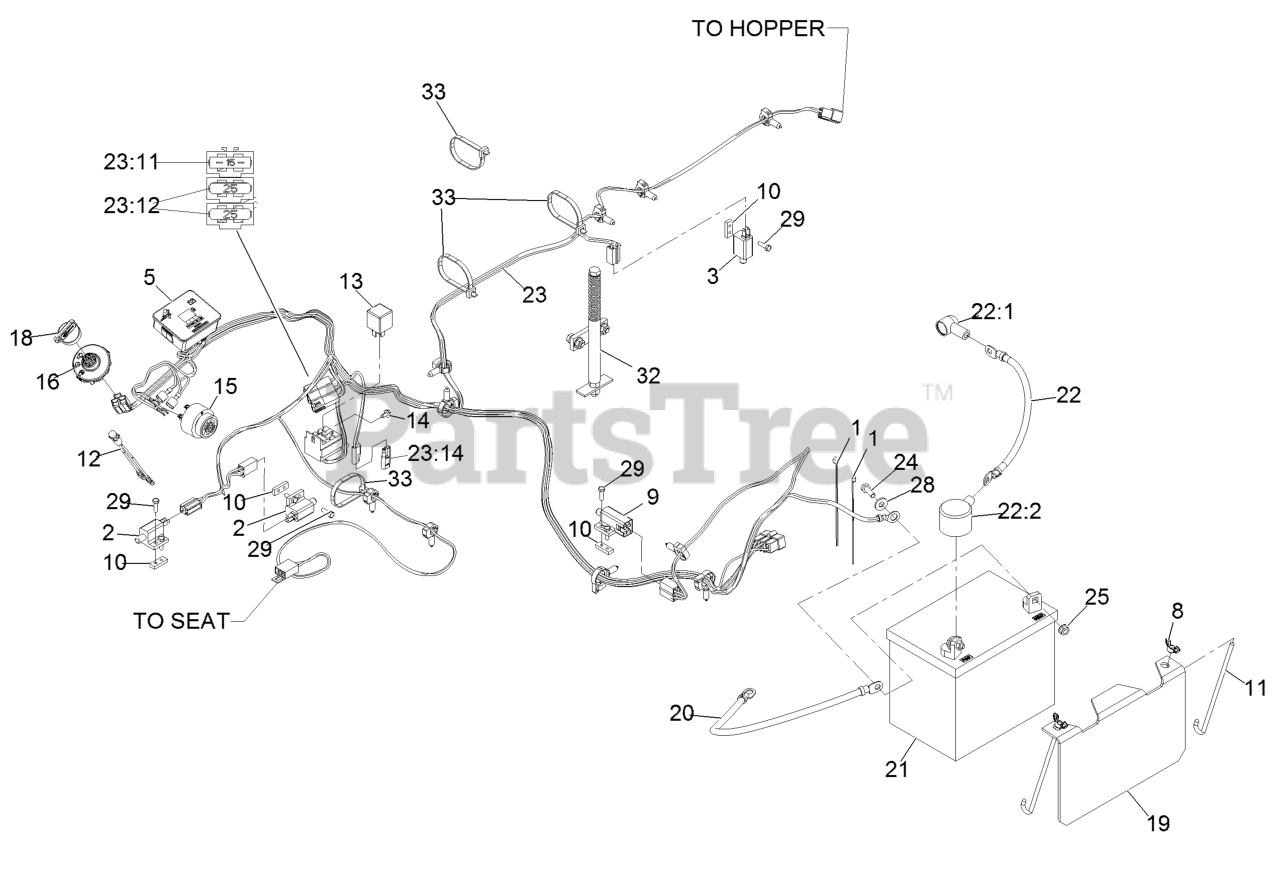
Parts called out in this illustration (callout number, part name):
1	TIE-CABLE
2	SWITCH-OPEN, NORMALLY
3	SWITCH-CLOSED, NORMALLY
5	HOUR METER ASM
8	WINGNUT
10	PLATE-TAPPED
11	BOLT-HOLDDOWN
12	INDICATOR-LED, RED
14	SCREW-HWH
15	ALARM-TONE, DUAL
18	KEY-IGNITION
19	HOLD DOWN-BATTERY
20	CABLE-BATTERY, NEGATIVE
21	Battery (300 Cca, Wet)
22	CABLE-BATTERY, POSITIVE
22:1	INSULATOR-SOLENOID
22:2	INSULATOR-BATTERY
23	HARNESS-WIRING
23:11	FUSE-BLADE, 15 AMP
23:12	FUSE-BLADE, 25 AMP
23:14	CAP-PLUG
24	SCREW-HH
28	WASHER-FLAT
32	HOPPER SWITCH ACTUATOR AS
33	TIE-PLASTIC
